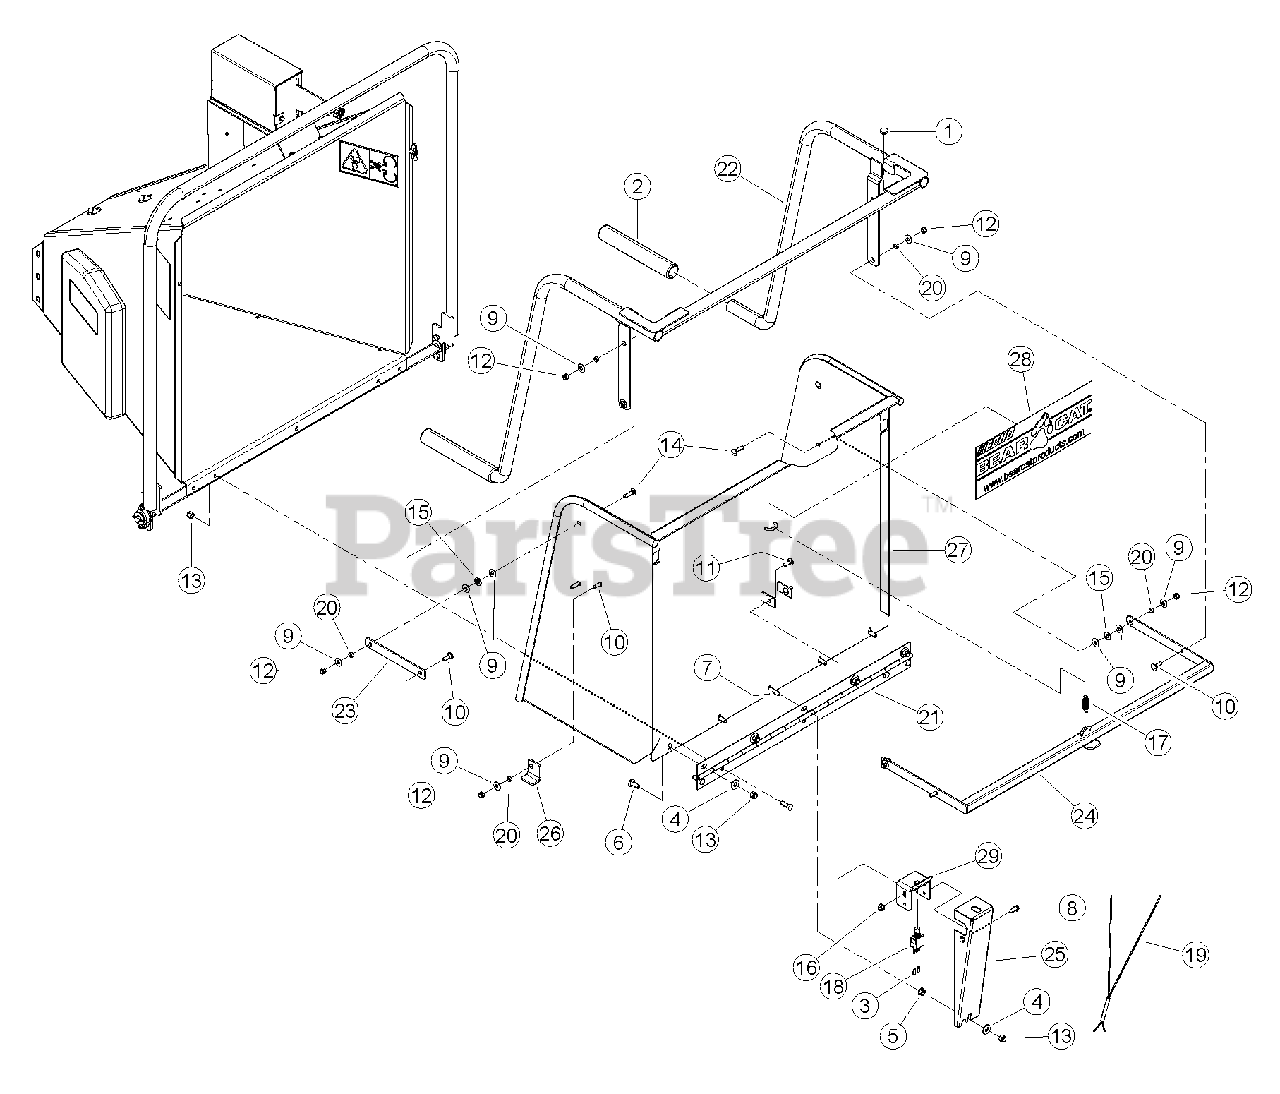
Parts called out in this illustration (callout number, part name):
1	BUMPER, RUBBER
2	GRIP, 1.219 X 10.00
3	CONNECTOR, 1/4 QD MALE
4	WASHER, 3/8 FLAT ZP
5	NUT, 3/8 SERRATED FLANGE ZP
6	BOLT, 3/8 X 1 CRG GR5 NC ZP
7	BOLT, 3/8 X 1-1/2 CRG GR5 NC ZP
8	SCREW, 11/32 X 7/8 HWH AB THREAD ZP
9	WASHER, 5/16 FLAT ZP
10	BOLT, 5/16 X 1 CRG GR5 ZP
11	BOLT, 5/16 X 7/8 CRG GR5 NC ZP
12	NUT, 5/16 NE NYLOCK ZP
13	NUT, 3/8 NE NYLOCK ZP
14	BOLT, 5/16 X 1-1/4 CRG GR5 ZP
15	WASHER, 5/16 ID. X 7/8 OD. NYLON FLAT
16	NUT, 5/16-18 NYLOCK-FLANGE
17	SPRING 1/2 X 2.00 LG,ZP
18	SWITCH, MOMENTARY IP67 NORMALLY ON
19	HARNESS, SAFETY BAR
20	SPACER, IDLER PIVOT
21	HINGE, EXTENSION TRAY
22	WELDMENT, KNEEBAR
23	LINK, PARALLEL
24	WELDMENT, KNEEBAR PIVOT
25	SHIELD, KNEEBAR SWITCH
26	LOCK, SAFETY BAR
27	ASSEMBLY, EXTENSION TRAY SERVICE PART
28	DECAL, BEARCAT WEB
29	BRACKET, SWITCH
